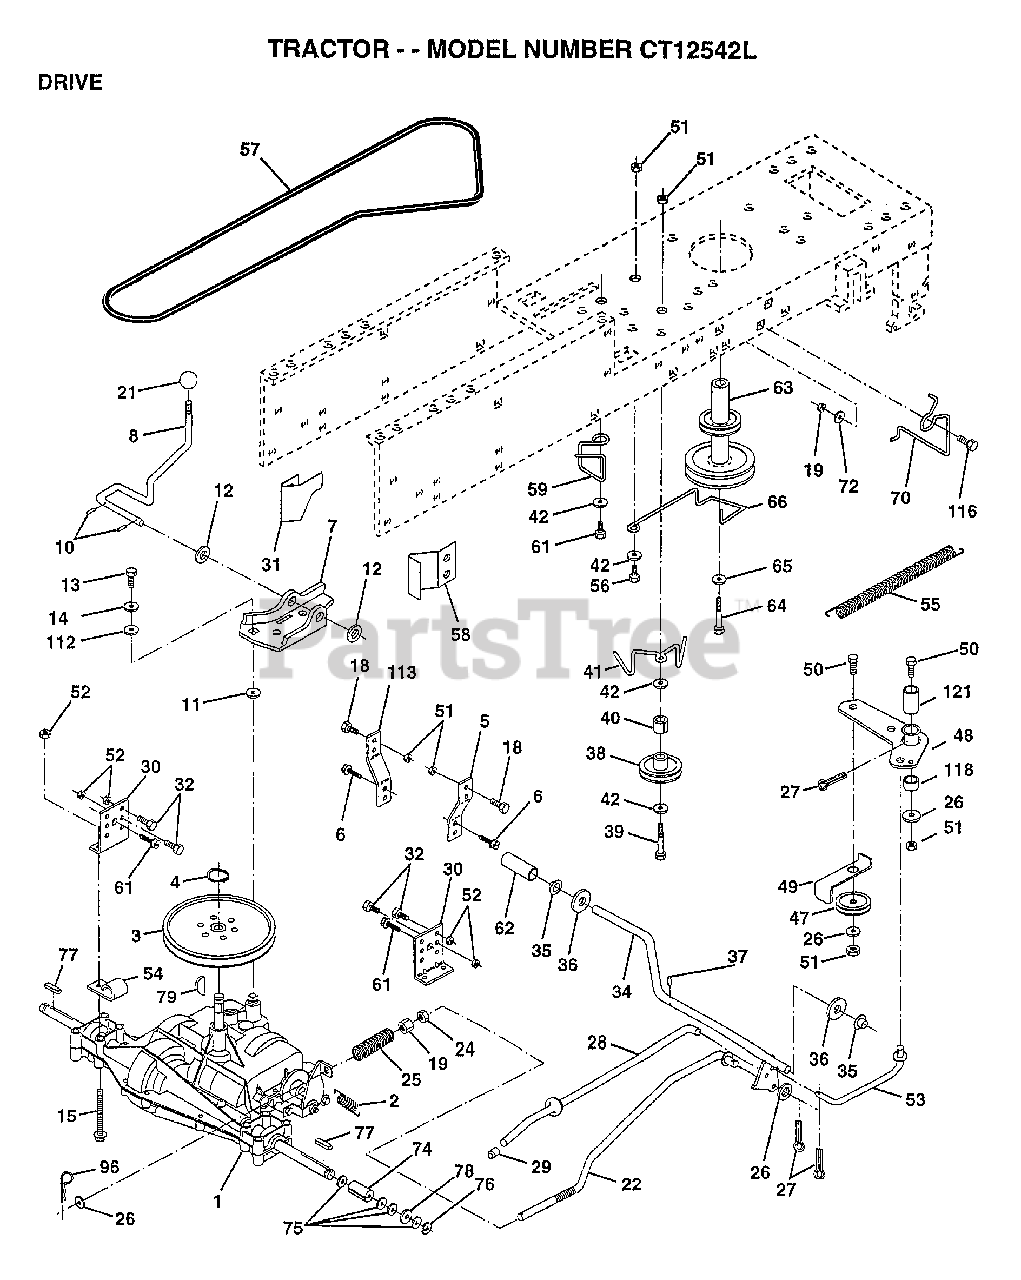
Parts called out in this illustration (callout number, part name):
1	TRANSAXLE, PEERLESS
2	SPRING.BRAKE.RETU
3	PULLEY TRANS
5	STRAP TORQUE
6	SCREW
8	SHIFT ROD
10	PIN COTTER 1/8
11	WASH-SHFT PLT LT
12	WASHER
13	BOLT.1/4-28.W/PAT
14	LOCKWASHER
15	BOLT.HX.FLG.5/16
18	BOLT
19	NUT
21	KNOB T (1/2-HOLE)
22	BRAKE ROD
24	NUT
25	SPRING ROD LT
26	WASHER
27	COTTER PIN
28	ROD.BRAKE.PARK.LT
29	PLUNGER CAP T
30	TRANSAXLE MTG BKT
31	"KEEPER,BELT LH T"
32	BOLT
34	SHAFT ASM-PEDAL F
35	NYLON BEARING
36	WASHER LT
38	PULLEY.IDLER.FLAT
39	BOLT
40	SPACER T
42	WASHER
48	BELLCRANK ASM
49	RETAIN BELT
53	"LINK, CLUTCH T"
54	CLIP T
55	"SPRING, RETURN LT"
58	"KEEPER,BELT RH T"
59	KEEPER BELT CNTSP
61	SCREW
62	PEDAL COVER T
63	PULLEY.ENGINE
64	BOLT
65	LOCKWASHER
66	KEEPER-BELT
70	KEEPER BELT ENG
72	WASHER
74	SPACER AXLE
75	WASHER
76	E-RING LT
77	SQUARE KEY
78	WASHER
96	RETAINER M
112	WASHER LT
113	"STRAP,TORQUE"
116	BOLT RDHD 3/8-16
118	SPACER-BELLCRANK
121	NYLINER-CLUTCHING
